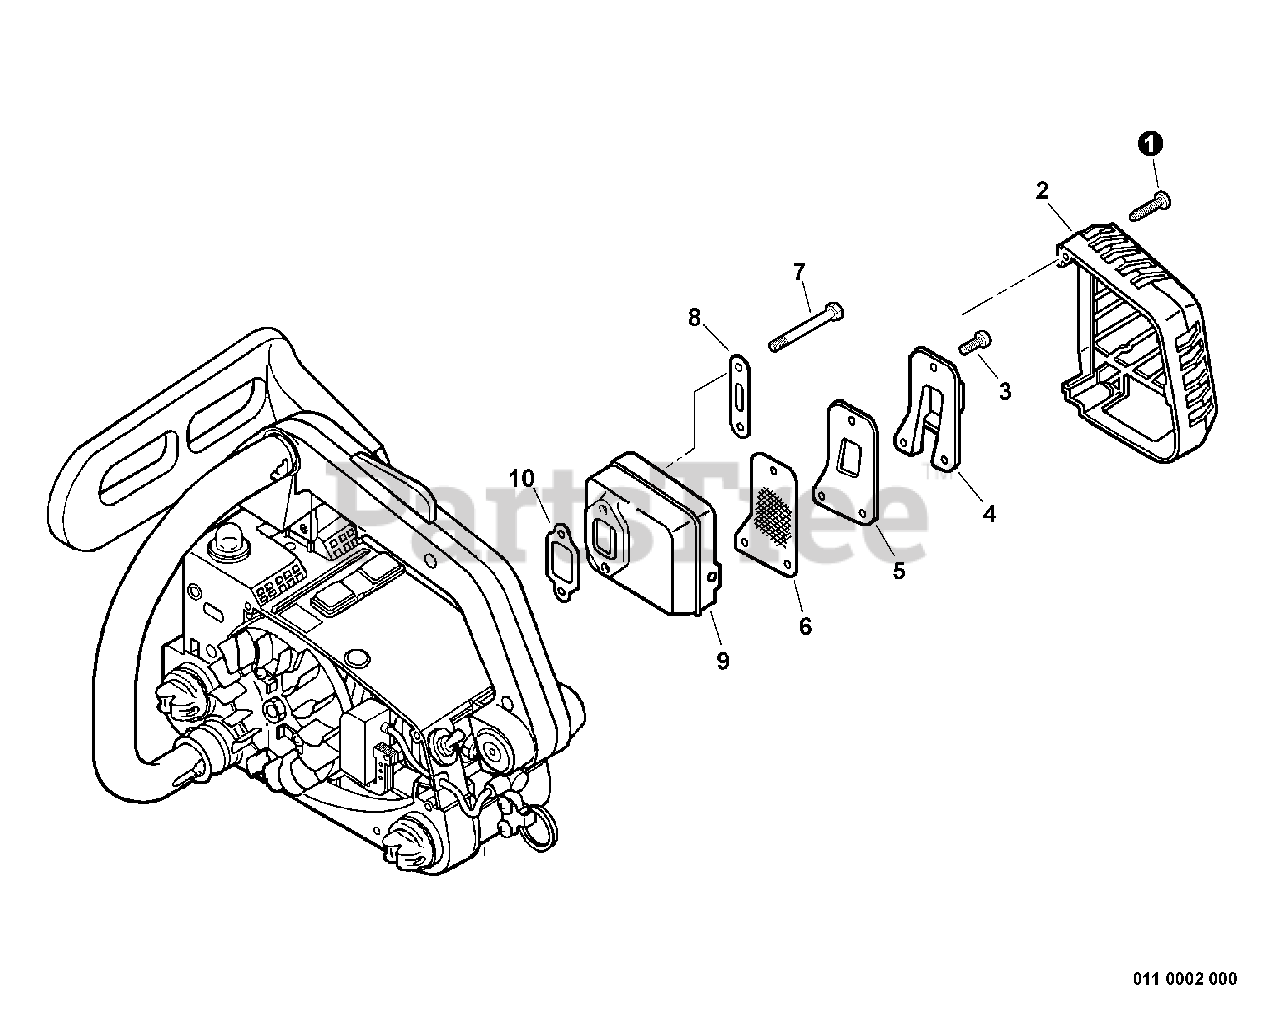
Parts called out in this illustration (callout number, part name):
1	SCREW - 5X20 -- TAPPING
2	COVER, EXHAUST
3	SCREW - 4X10
4	GUIDE, EXHAUST
5	GASKET, EXHAUST
6	SCREEN, SPARK ARRESTOR
7	SCREW - 5X45
9	MUFFLER
10	GASKET, EXHAUST
